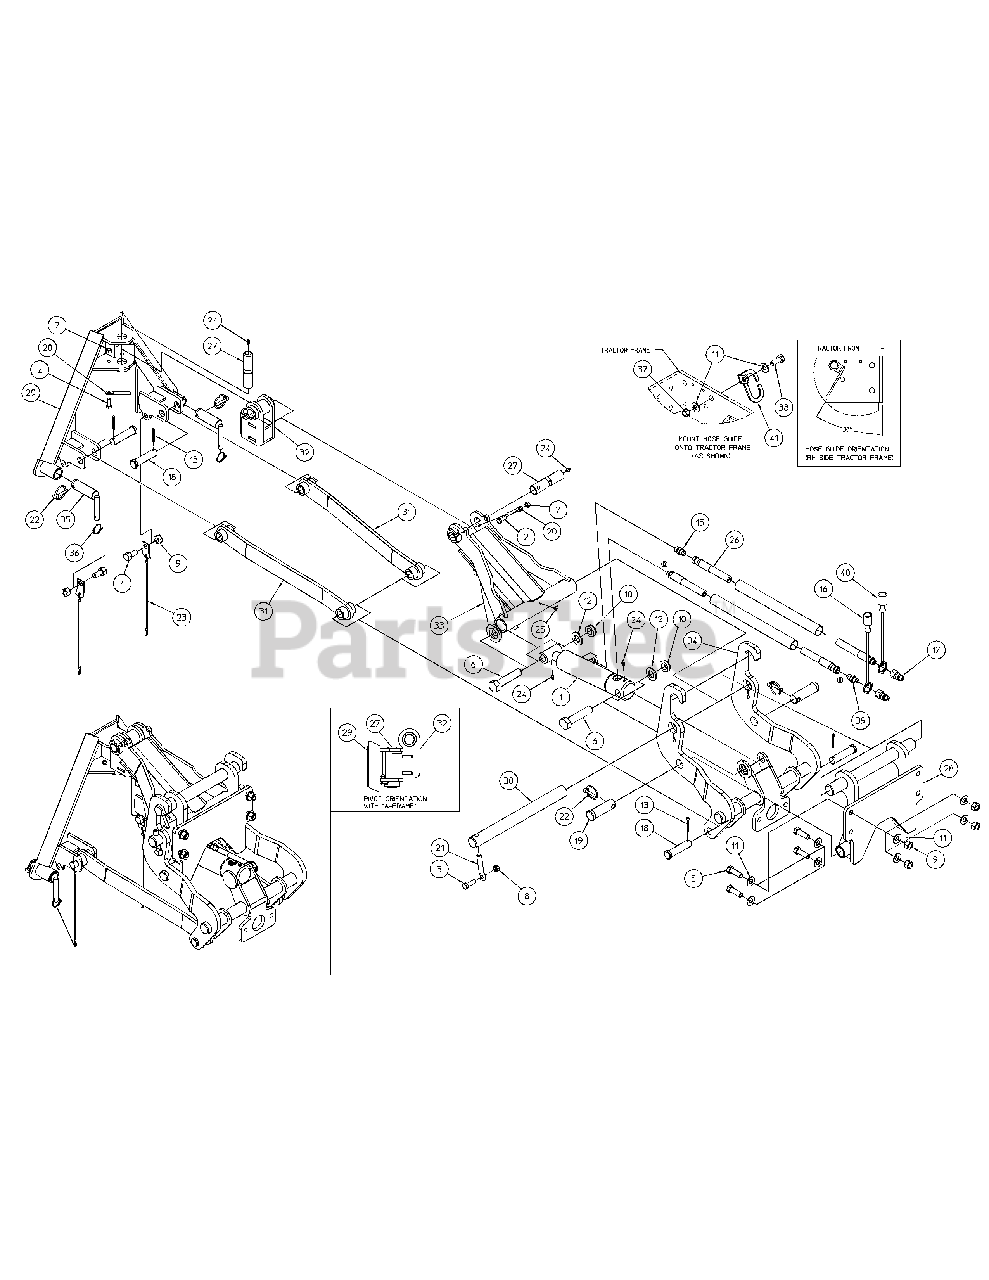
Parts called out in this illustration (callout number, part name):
1	ASSY-HYDRAULIC CYLINDER (LIFT)
2	HEX HEAD CAP SCREW 5/16-24X.875 G5 ZY
3	HEX HEAD CAP SCREW 3/8-24X1.25 G5 ZY
4	HEX HEAD CAP SCREW 1/2-20X1.0 G5 SAE ZY
5	HEX HEAD CAP SCREW 1/2-20X1.50 G5 ZY
6	HEX HEAD CAP SCREW 3/4-16X3.75 G5
7	NUT HEX 5/16-24 ZY LOCK
8	NUT HEX 3/8-24 ZY LOCK
9	NUT HEX 1/2-20 G5 ZY LOCK
10	NUT HEX 3/4-16 ZY JAM
11	FLAT WASHER 1/2 SAE HARD ZY
12	FLAT WASHER 3/4 .812X1.469X.134 SAE ZY
13	PIN-COTTER 3/16X1.25 ZY HARDENED
15	UNION STRAIGHT 06MX06M ORBXJIC
16	CAP-DUST (BLUE)
17	COUPLER-NOSE
18	PIN-CLEVIS (3/4 DIA X 3)
19	PIN-CLEVIS (1 DIA X 3)
20	PIN-RETAINER
21	PIN-RETAINER
22	LINCH PIN,1/4 DIA X 1.25 SHAFT
23	CABLE ASSEMBLY
24	FITTING-STRAIGHT (GREASE) 1/4-28
25	FITTING-45 DEG (GREASE) 1/4-28
26	HOSE-HYD WITH SLEEVE (1/4 X 63)
27	PIN-PIVOT (BUCKET CYL-KNEE)
28	WELDMENT-HANGER (SC)
29	WELDMENT- MOUNT (A-FRAME)
30	SHAFT-PIVOT
31	WELDMENT-LINK
32	WELDMENT-PIVOT
33	WELDMENT-PIVOT LINK
34	WELDMENT-HITCH FRAME (SC)
35	WELDMENT-PIN
36	RING-LOCKING
37	NUT HEX M12-1.75 G8.8 ZY
38	HEX HEAD CAP SCREW M12X1.75X30 G10.9 ZY FTHD
39	UNION STRAIGHT 06MX06M ORBXJIC
40	CAP-DUST (RED)
41	PLATE-HOSE GUIDE
